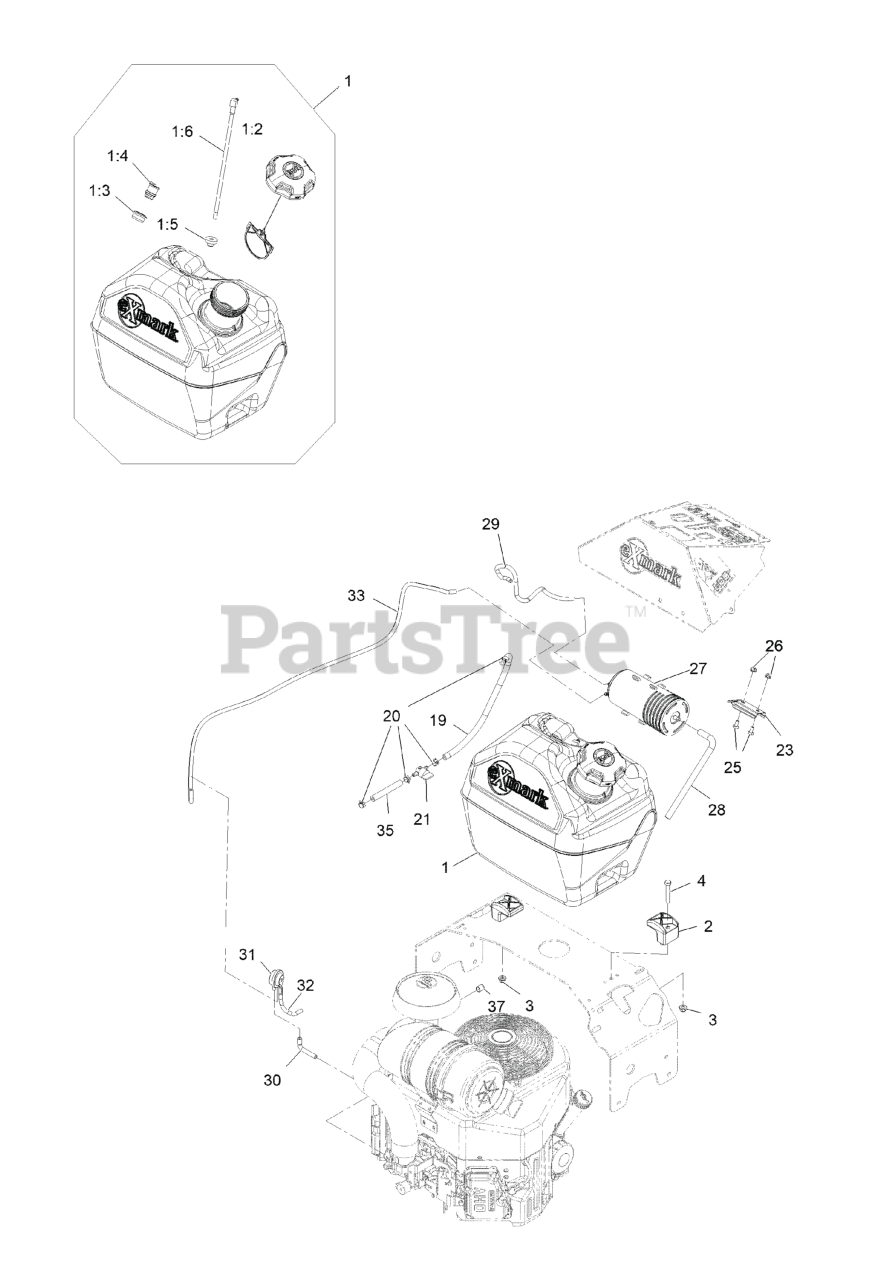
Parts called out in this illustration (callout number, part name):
1	ASM, FUEL TANK 5 GAL
1:2	CAP-FUEL, RATCHETING
1:3	GROMMET
1:4	VALVE-VENT, FUEL
1:5	BUSHING
1:6	FITTING, FUEL W/LINE AND SCREEN
3	NUT-HF, NI
4	SCREW-HH
19	HOSE-FUEL
20	CLAMP-HOSE
21	VALVE-FUEL
23	BRACKET-CANISTER, CARBON
25	SCREW-HH
27	CANISTER-CARBON, 800CC
28	HOSE-VENT, CANISTER
29	HOSE-EMISSIONS
30	HOSE-VENT, FORMED
31	VALVE-CONTROL, VACUUM
32	HOSE-VENT, FORMED
33	HOSE-VENT, FORMED
35	HOSE-FUEL
37	PLUG-PORT
